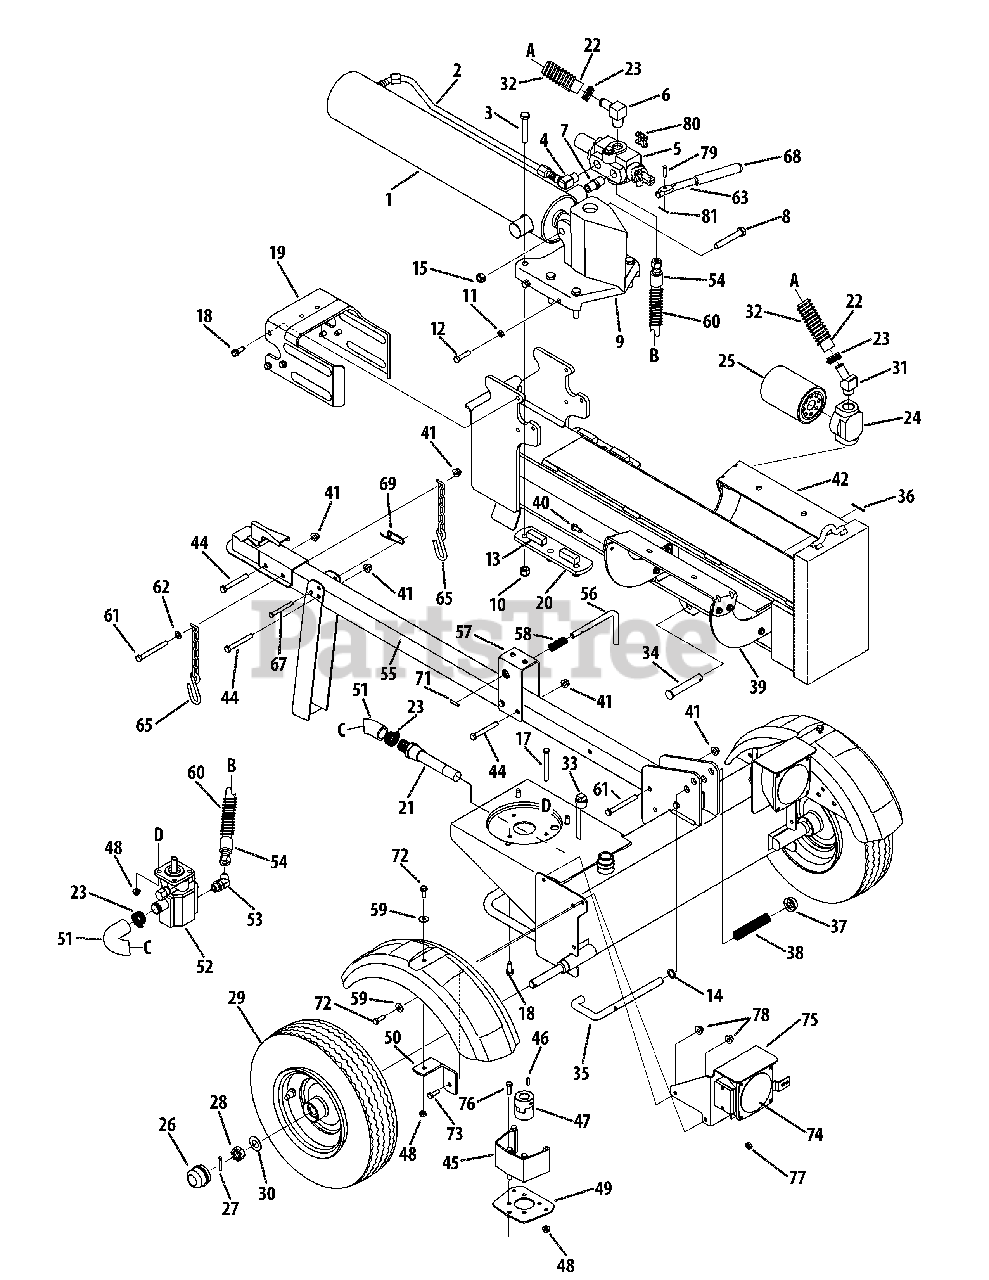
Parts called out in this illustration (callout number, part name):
1	Hydraulic Cylinder
1	Kit Seal 4.5" for XINGHUI cylinder 718-0769A
1	Kit Seal 4.5" for ENERGY cylinder 718-0769A
2	Hydraulic Tube
3	Hex Cap Screw, 1/2-20 x 2.75
4	90 Degree Solid Adapter
5	Control Valve
6	Return Elbow
7	Nipple Pipe, 1/2-14
8	Hex Cap Screw, 1/2-13 x 3.25
9	Wedge Assembly
10	Hex Lock Nut, 1/2-20
11	Hex Jam Nut, 3/8 -24
12	Hex Cap Screw, 3/8 -24 x 1.5
14	Flat Washer, .635 x.93 x.06
15	Hex Lock Nut, 1/2-13
17	Hex Screw, 5/16-18 x 3.25
18	Hex Washer Screw, 3/8 -16 x 1.0
21	Inlet Filter
22	Return Hose, 3/4" ID x 44" Lg.
23	Hose Clamp, 5/8 "
24	Filter Housing
25	Oil Filter
26	Hub Cap
27	Cotter Pin
28	Slotted Nut, 3/4-16
29	Wheel Assembly
30	Flat Washer, .760 ID x.500 OD
31	Adapter, 3/4-14
32	Hose Guard
33	Vented Dipstick
34	Clevis Pin
35	Lock Rod
36	Cotter Pin
37	Push Cap
38	Compression Spring
40	Hex Washer Screw, 5/16-18 x .750
41	Flange Lock Nut, 3/8 -16
43	Frame Assembly
44	Hex Bolt, 3/8-16 x 3"
45	Coupling Shield
46	Square Key, 3/16" x.75
47	Coupling, .500
47	Coupling, .875
48	Flange Lock Nut, 5/16-18
52	Gear Pump
53	45 Degree Elbow Fitting
54	High Pressure Hydraulic Hose
56	Latch Rod
58	Compression Spring
59	Flat Washer
60	Hose Guard
61	Hex Cap Screw, 3/8 -16 x 3.50
62	Flat Washer, .375 x.738 x.063
63	Hydraulic Valve Control
64	Hitch Coupling Assembly
66	Fender
67	Clevis Pin
69	Spring Pin
72	TT Screw, 5/16-18 x 0.875"
73	TT Screw, 5/16-18 x 1.00
74	Light Kit
76	Hex Screw, 5/16-18 x 1.00
77	Jam Nut, 3/8 -16
78	Speed Nut, .3125 ID
79	Clevis Pin
80	Valve Handle Link
81	Cotter Pin
